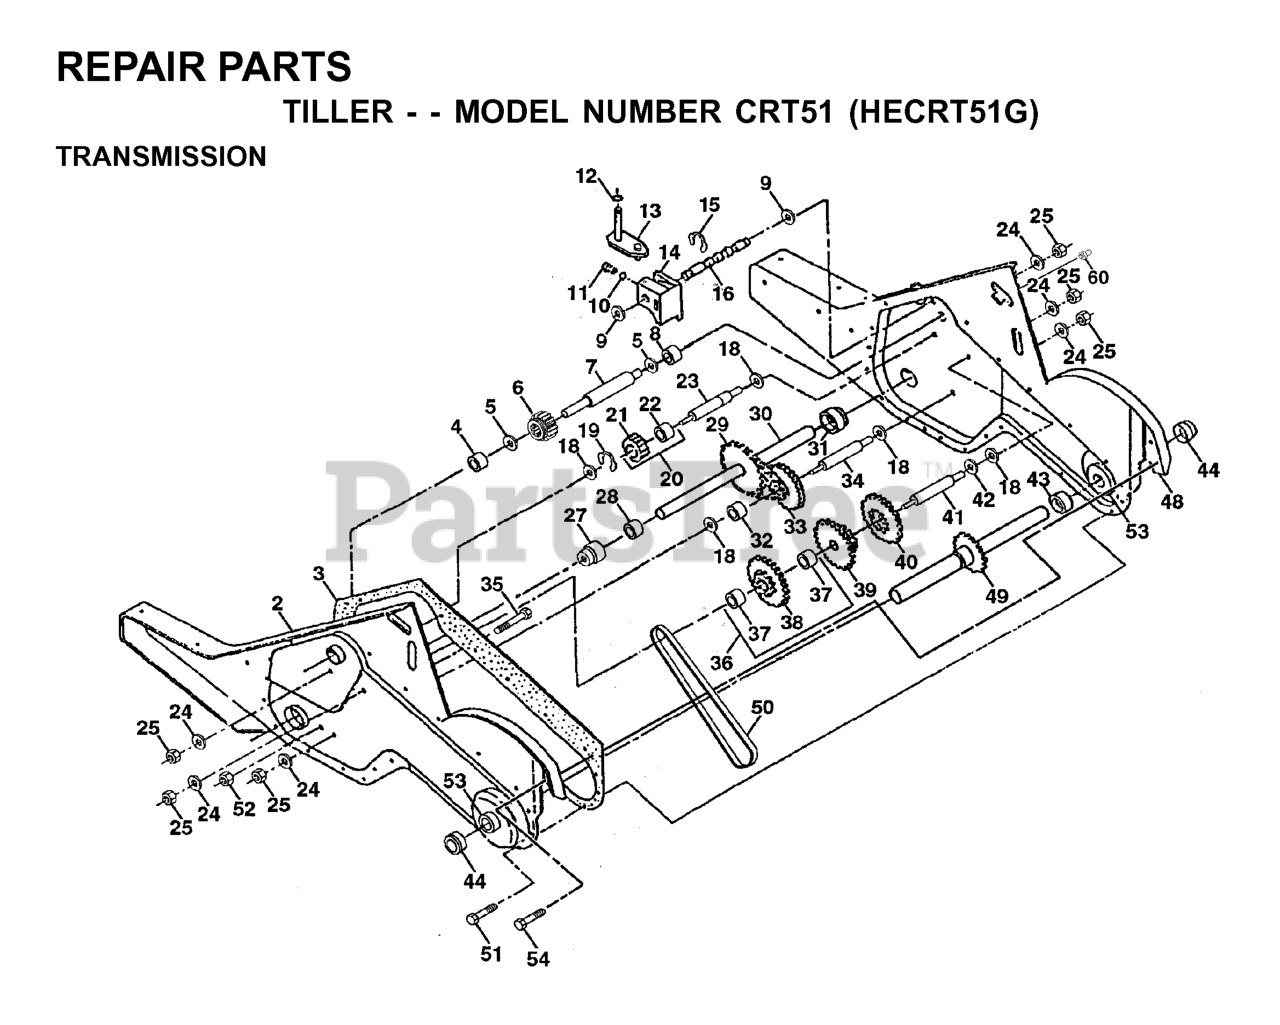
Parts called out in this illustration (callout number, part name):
1	TRANSMISSION ASSY
2	GEARCASE-LH
3	GASKET
4	NEEDLE BRNG LT
5	THRUST WASHER
6	GEAR.PINION.INPUT
7	SHAFT.INPUT."D".TILLER
8	BEARING TI
9	WASHER, SEAL (2 2)
10	STEEL BALL KIT
11	SPRING-SHIFT CRT
13	BRACKET ASM.SHIFT.CRT
14	SHIFT FORK TI
16	SHAFT.SHIFTER.TILLER
20	GEAR ASSY CRT
21	GEAR-REV IDLR CRT
22	NEEDLE BEARING TI
24	LOCKWASHER
25	NUT.ASF.HEX.7/16
27	BEARING, SHAFT LH CRT
30	GROUND SHAFT ASS'Y
31	BEARING, SHAFT RH CRT
33	SPRCKT 8 GEAR CRT
34	SHAFT.SECONDARY.REDUCTION.CRT
35	SCRW WHIZ LOK CRT
36	SPROCKET.ASM.W/BEARING.TILLER
37	BEARING
38	SPROCKET, TINE
41	SHAFT.REDUCTION.TILLER
42	BRNG RACE T
44	SEAL ASM, OIL
48	GEARCASE
49	TINE SHAFT
50	CHAIN.TILLER
51	SCREW
53	KIT.BEARING.TILLER.
54	SCREW 1/4-20X3/4
60	ZERK M
